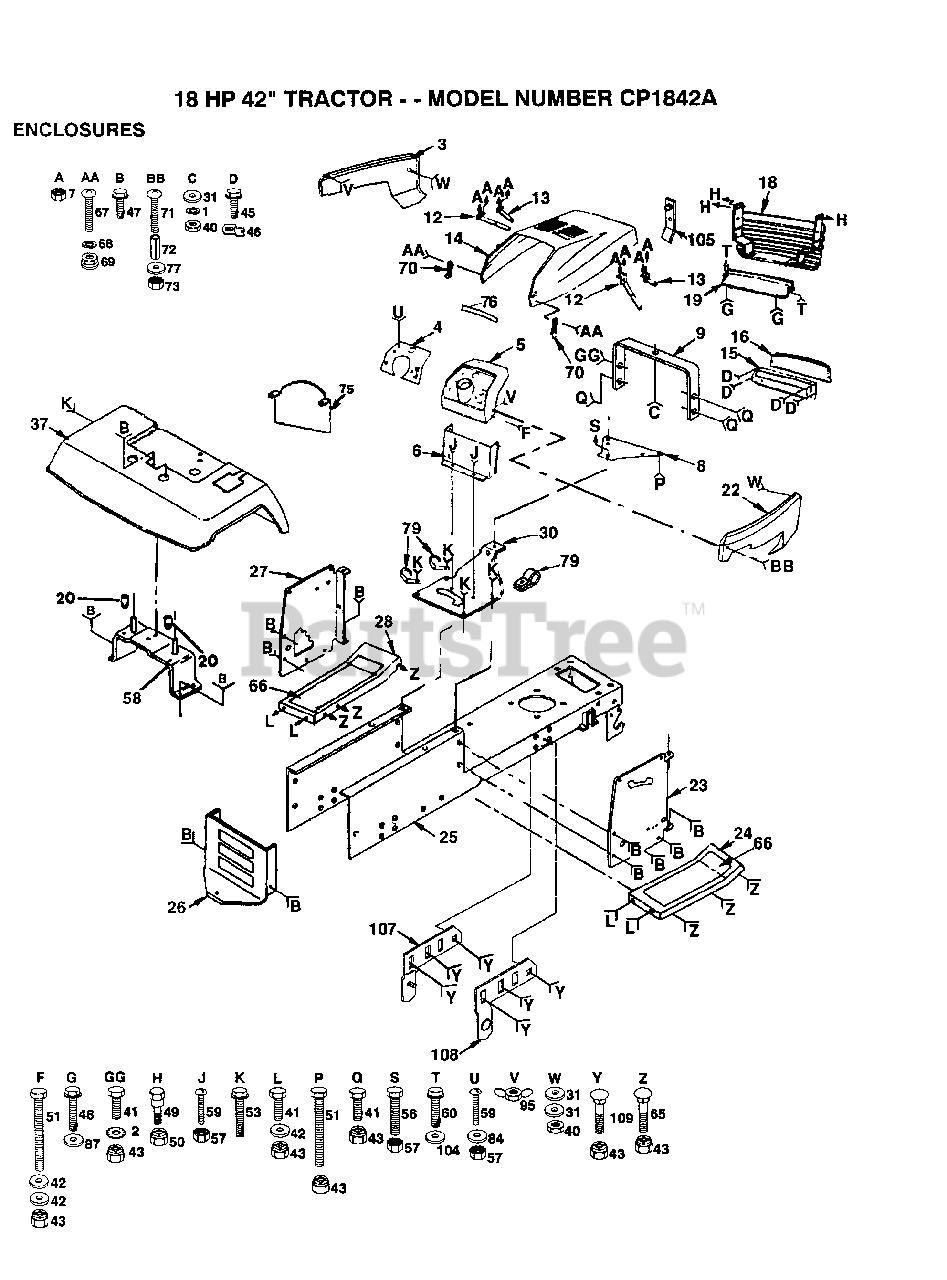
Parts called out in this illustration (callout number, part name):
1	LOCKWASHER
2	LOCKWASHER
3	"PANEL,SIDE LH"
4	DASH PLATE
7	NUT
9	SUPPORT ASS'Y
10	PLUG BUTTON T
16	LENS LT
22	"PANEL,SIDE RH"
27	DASH PANEL LH
31	WASHER PM
42	WASHER
46	"""J"" FASTENER LT"
47	SCREW
48	SCREW
53	SCREW LT
56	BOLT
59	SCREW
60	SCREW HEX CRT
65	BOLT
66	FOOTREST PAD
67	SCREW
68	LOCKWASHER
69	WELDNUT
70	HOOD LATCH T
71	SCREW
72	SPACER LT
77	WASHER
79	CLIP T
84	WASHER
87	WASHER
104	WASHER
107	PIVOT BRKT LH
108	PIVOT BRKT RH
109	BOLT
